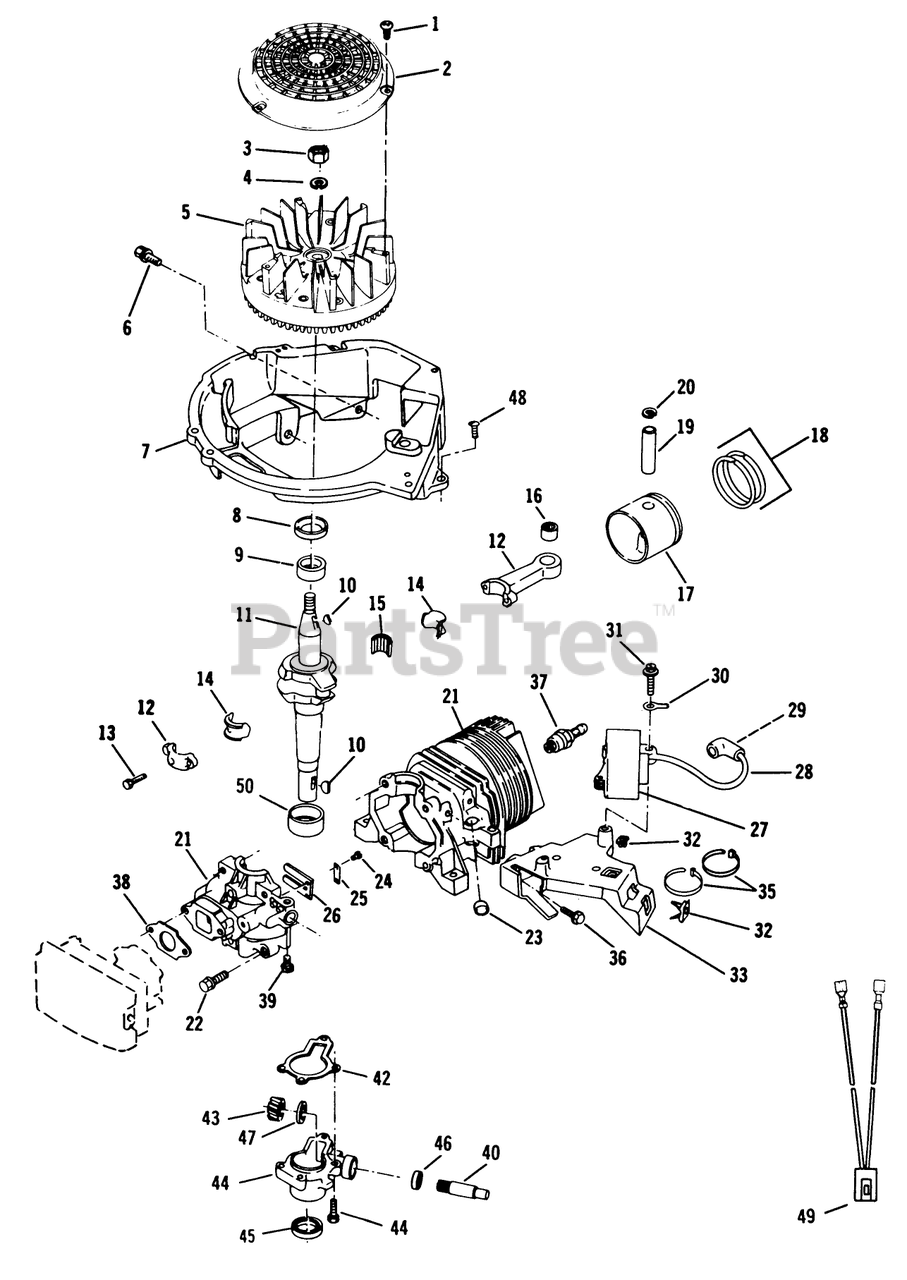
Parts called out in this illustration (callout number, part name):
1	SCREW F
2	Screen-Flywheel
3	NUT
6	SCREW-SEMS
9	BEARING V
10	KEY
13	SCREW-HSH
14	LINER ASM
16	BEARING AY F
20	RING-RETAINING
22	SCREW S
23	PLUG-CORE VF
25	PLATE-BACKUP, REED
28	HT LEAD&COVER XEV
30	TERMINAL S
32	NUT-CLIP
38	GASKET CARB S
42	GASKET S
43	GEAR, DR SHAFT S
45	SEAL-OIL
46	SEAL S
47	THRUST WASHER
48	SCREW F
50	BEARING S
